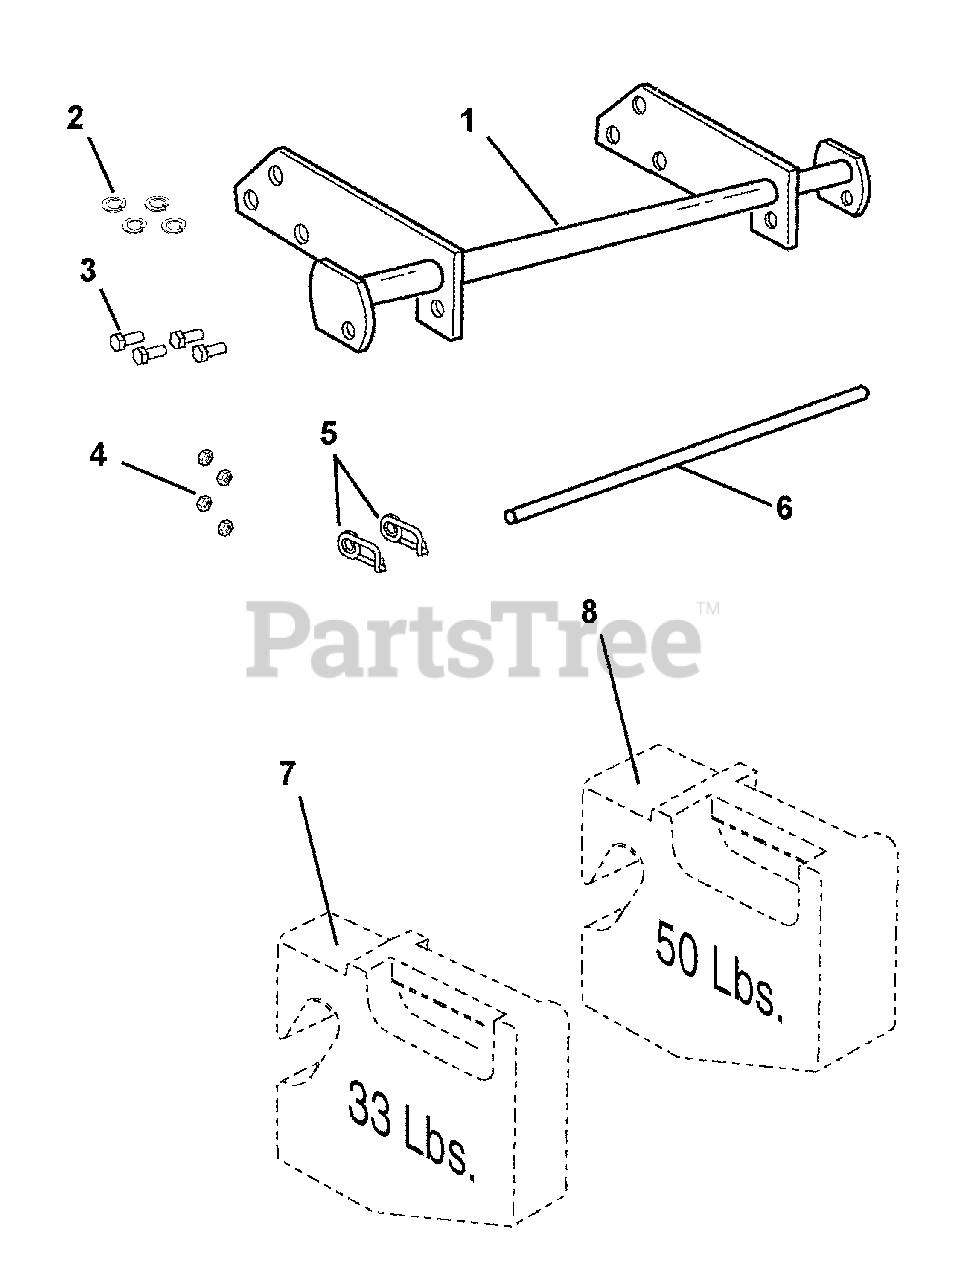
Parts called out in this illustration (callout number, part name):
2	WASHER, Lock, 1/2
3	CAPSCREW, Hex Head, 1/2 - 13 x 1-1/2
4	NUT, Hex, 1/2 - 13
5	CLIP, Safety
6	ROD, Locking
7	WEIGHT, Suitcase, 33 lbs.
8	WEIGHT, Suitcase, 50 lbs.
